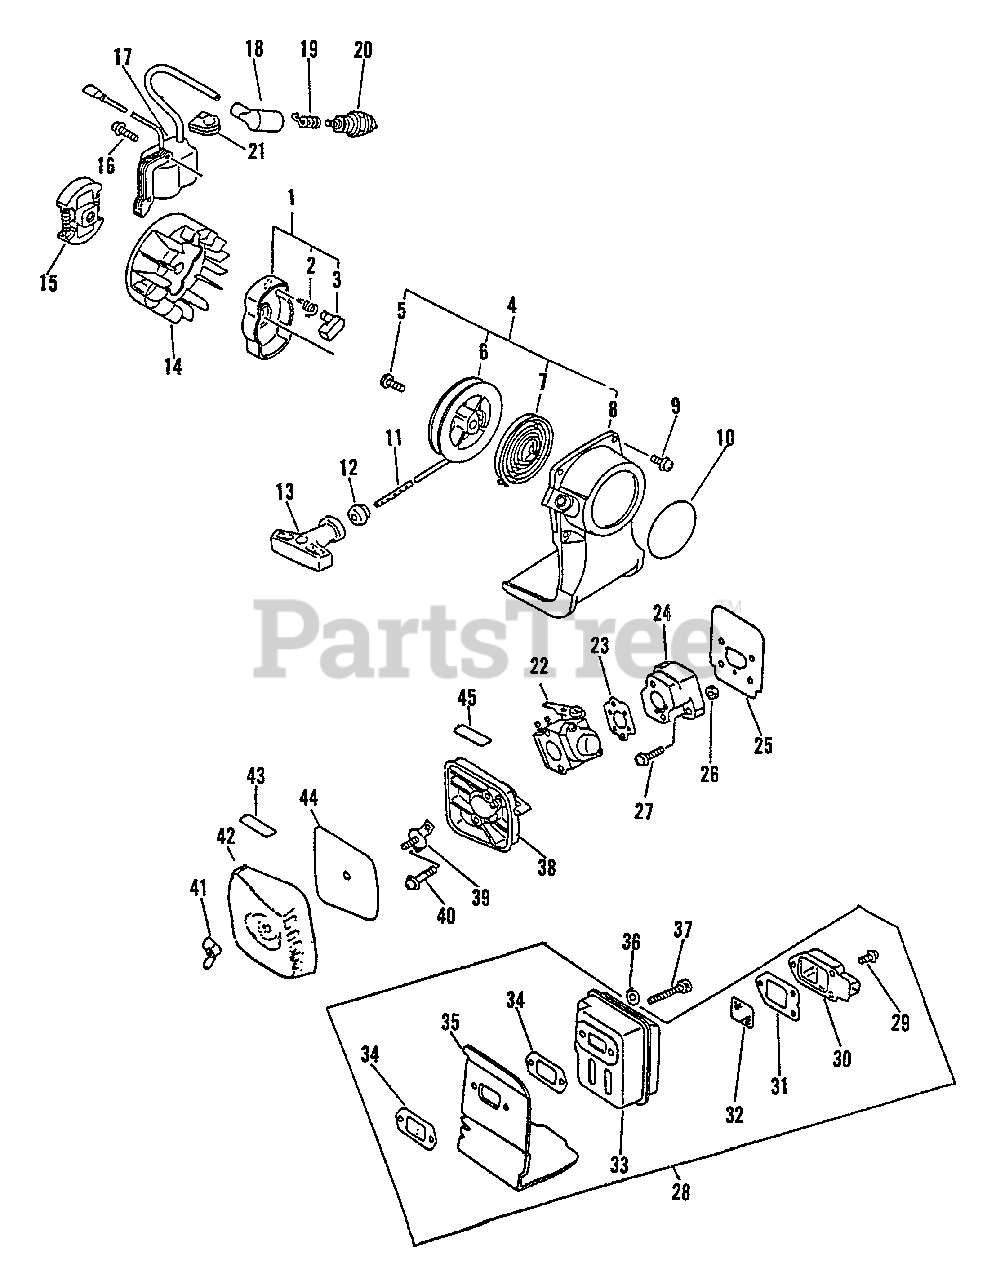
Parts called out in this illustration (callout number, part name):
1	Pawl Asy, Starter
2	Spring, Return
3	Pawl, Starter
4	Starter Asy
6	Drum, Starter
7	Spring, Rewind
8	Case, Starter
9	Screw 4X16
10	Label, Echo
11	Rope, Starter
12	Guide, Rope
13	Grip, Starter
14	Flywheel
15	Clutch Asy
16	Screw 4X22
17	Coil Ignition
18	Cap, Spark Plug
19	Coil, Spark Plug Cap
20	Plug, Spark BPM-7A
22	Carburetor C1U-K16
23	Gasket, Intake
24	Insulator
25	Gasket, Intake
27	Screw 5X20
28	Muffler Asy
29	Screw 4X10
30	Holder, Screen
31	Gasket, Muffler Lid
32	Screen, Muffler
33	Muffler
34	Gasket, Muffler
35	Cover, Muffler
36	Washer 5
37	Bolt, H.S. 5X55
38	Case, Air Cleaner
39	Plate, Prevent
40	Screw 5X64
41	Nut, Wing 5
42	Cover, Air Cleaner
43	Label. Caution
44	Filter, Air
45	Label, Choke
